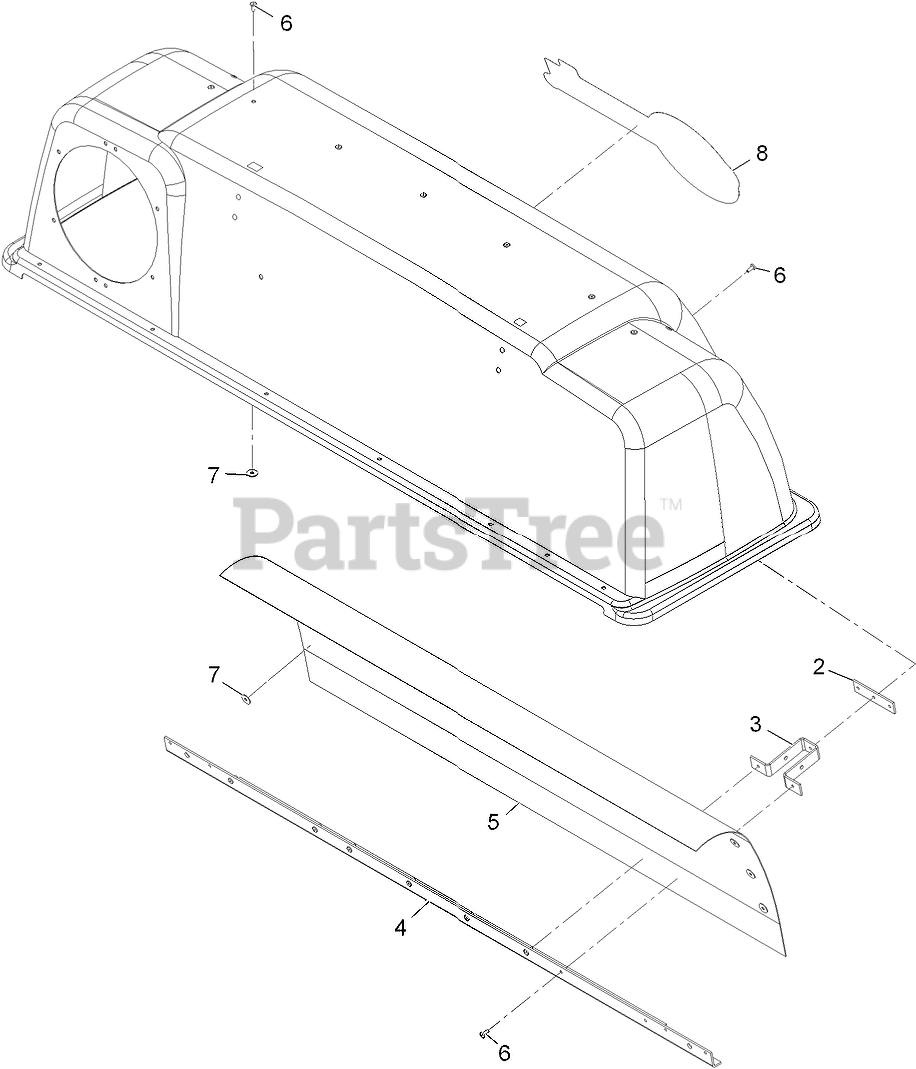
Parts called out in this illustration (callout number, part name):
2	PLATE-LATCH, REINFORCEMEN
3	BRACKET-MOUNT
4	SUPPORT-SCREEN
5	SCREEN-BAGGER
6	RIVET-BLIND
7	WASHER-FLAT
8	DECAL-EXMARK LOGO
